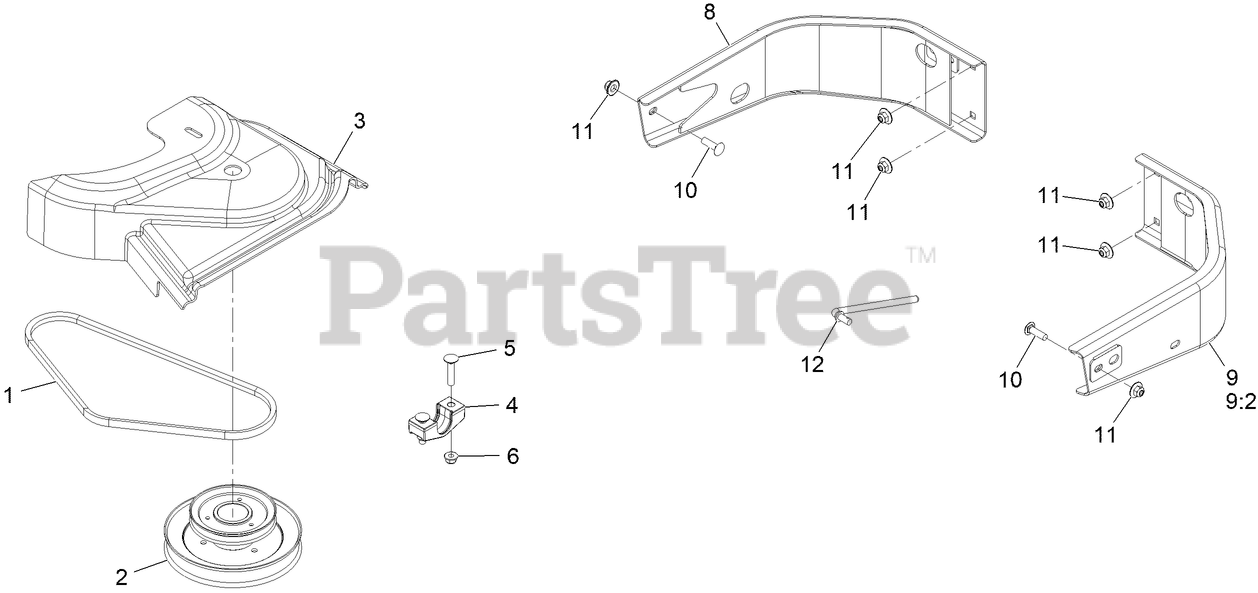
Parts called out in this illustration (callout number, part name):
2	JACKSHAFT,UV DRIVE 604 SPLINED
3	COVER,BELT UV 60
4	SUPPORT-BEARING CROSS SHAFT
5	SCREW-CARR
6	NUT-HF, NI
8	BUMPER-RH
9	LH BUMPER ASM
9:2	DECAL-WARNING
10	Bolt-Carriage 3/8-16 X 1 1/4
11	Nut-Nyloc 3/8-16 Flg
12	LINK-HANDLE
